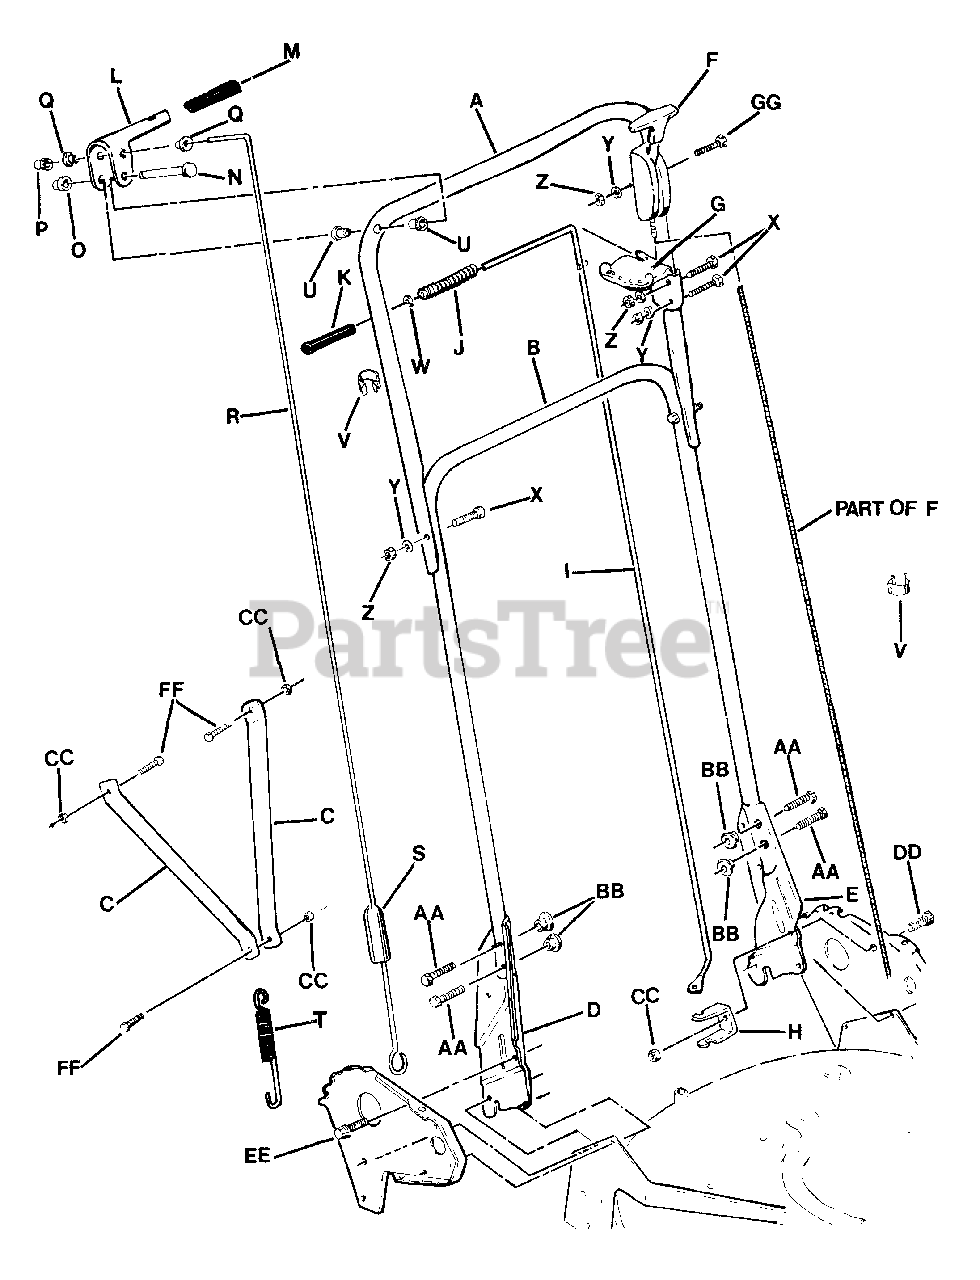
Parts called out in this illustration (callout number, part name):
A	HANDLE, Upper
B	HANDLE, Middle
C	STRAP, Handle
D	MOUNT, Right Hand Handle
E	MOUNT, Left Hand Handle
F	CONTROL, Throttle (Briggs)
G	SECTOR, Speed Control
H	ANCHOR, Speed Control
I	LEVER, Speed Control
J	SPRING, Speed Control Lever
K	GRIP, Speed Control Lever
L	HANDLE, Clutch
M	GRIP, Clutch Handle
N	PIN, Clutch handle
O	NUT, 1/4" Push
P	NUT, 1/8" Push
Q	BUSHING, Pull Rod (Nylon)
R	ROD, Clutch Pull
S	COVER, Vinyl
T	SPRING, Clutch
U	BUSHING, Clutch Handle Pin
W	WASHER, 5/16" SAE Flat
X	SCREW, 1/4-28 x 1-3/8" Hex Head Cap, Grade 5
Y	WASHER, 1/4" Internal/External Tooth Lock
Z	NUT, 1/4-28 Hex
AA	SCREW, 1/4-20 x 1" Hex Head Cap, Grade 5
BB	NUT, 1/4-20 Curved Head
CC	NUT, 5/16-24 Hex Center Lock
DD	SCREW, 5/16-24 x 1" Hex Head Cap, Grade 5
EE	SCREW, 5/16-24 x 1-1/4" Hex Head Cap, Grade 2
FF	SCREW, 5/16-24 x 3/4" Hex Head Cap, Grade 5
GG	SCREW, 5/16-28 x 1-3/4" Hex Head Cap, Grade 5
